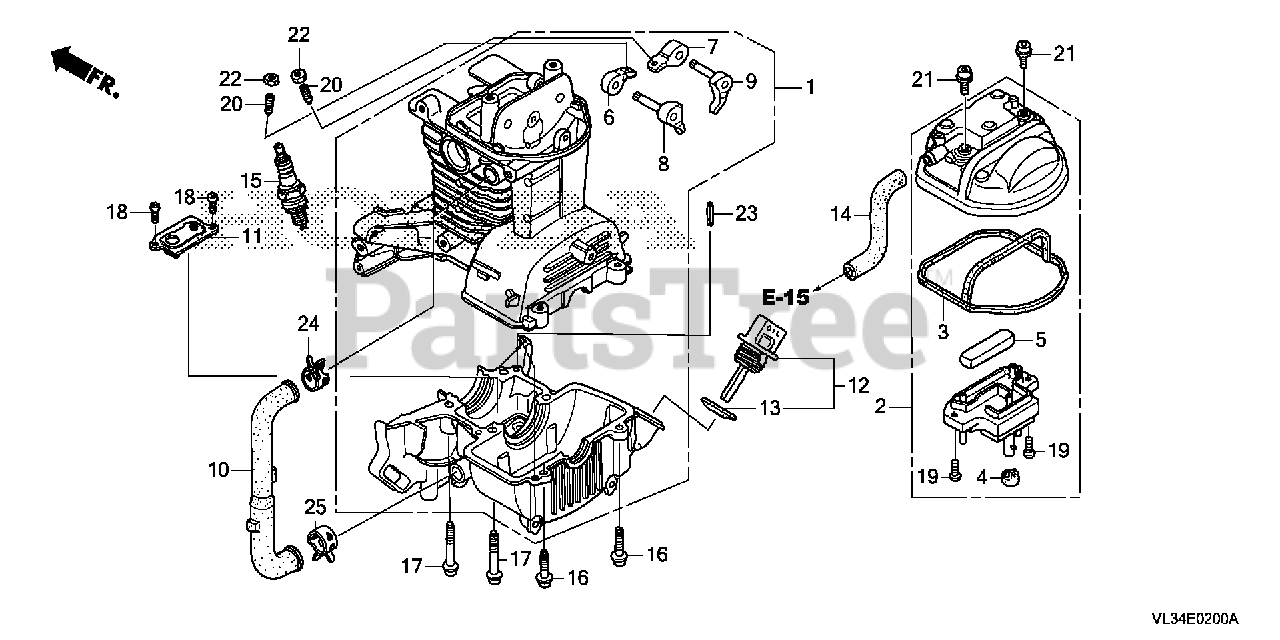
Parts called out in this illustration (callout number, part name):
1	CRANKCASE SET
2	COVER, CYLINDER HEAD
3	SEAL, HEAD COVER
4	GROMMET, HEAD COVER
5	FILTER, BREATHER
6	ARM, IN. VALVE ROCKER
7	ARM, EX. VALVE ROCKER
8	LIFTER, IN. VALVE
9	LIFTER, EX. VALVE
11	PLATE ASSY., OIL OUTLET VALVE
12	CAP ASSY., OIL FILLER
13	GASKET, OIL FILLER CAP
14	TUBE, BREATHER
15	SPARK PLUG (CMR4H) (NGK)
15	SPARK PLUG (CMR5H) (NGK)
15	SPARK PLUG (CMR6H) (NGK)
16	BOLT, SOCKET (5X20)
17	BOLT, SOCKET (5X32)
18	SCREW, PAN (4X8)
19	SCREW, PAN (4X8)
20	SCREW, TAPPET ADJUSTING
21	BOLT, SOCKET (5X12)
22	NUT, TAPPET ADJUSTING
23	PIN, SPRING (4X10)
24	CLAMP, TUBE (D12)
25	CLAMP, TUBE (D13)
